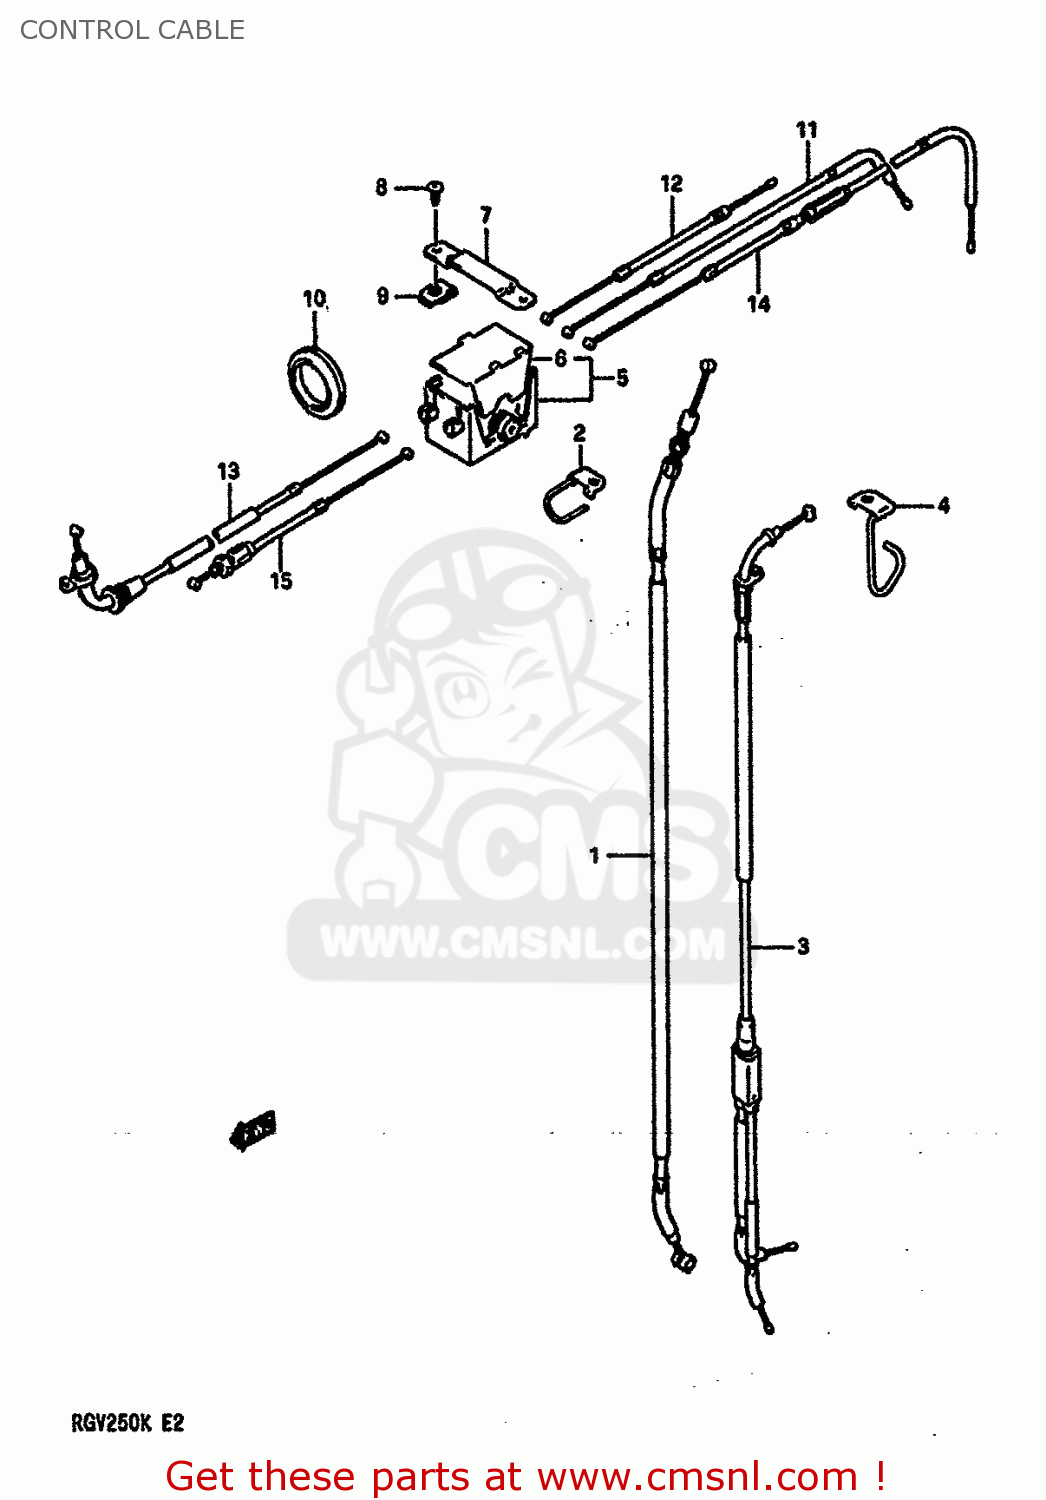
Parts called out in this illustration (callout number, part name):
1	CABLE ASSY,CLUTCH
2	GUIDE,CLUTCH CABLE
3	CABLE,STARTER
4	GUIDE,STARTER CABLE
5	BOX,THROTTLE CABLE CONNECT
6	COVER,THROTTLE CABLE CONN
7	PLATE,CONNECT BOX
8	SCREW
9	NUT
10	GROMMET
11	CABLE,THROTTLE NO.1
12	CABLE,THROTTLE NO.2
13	CABLE,THROTTLE NO.3
14	CABLE,THROTTLE NO.4
15	CABLE,THROTTLE NO.5
